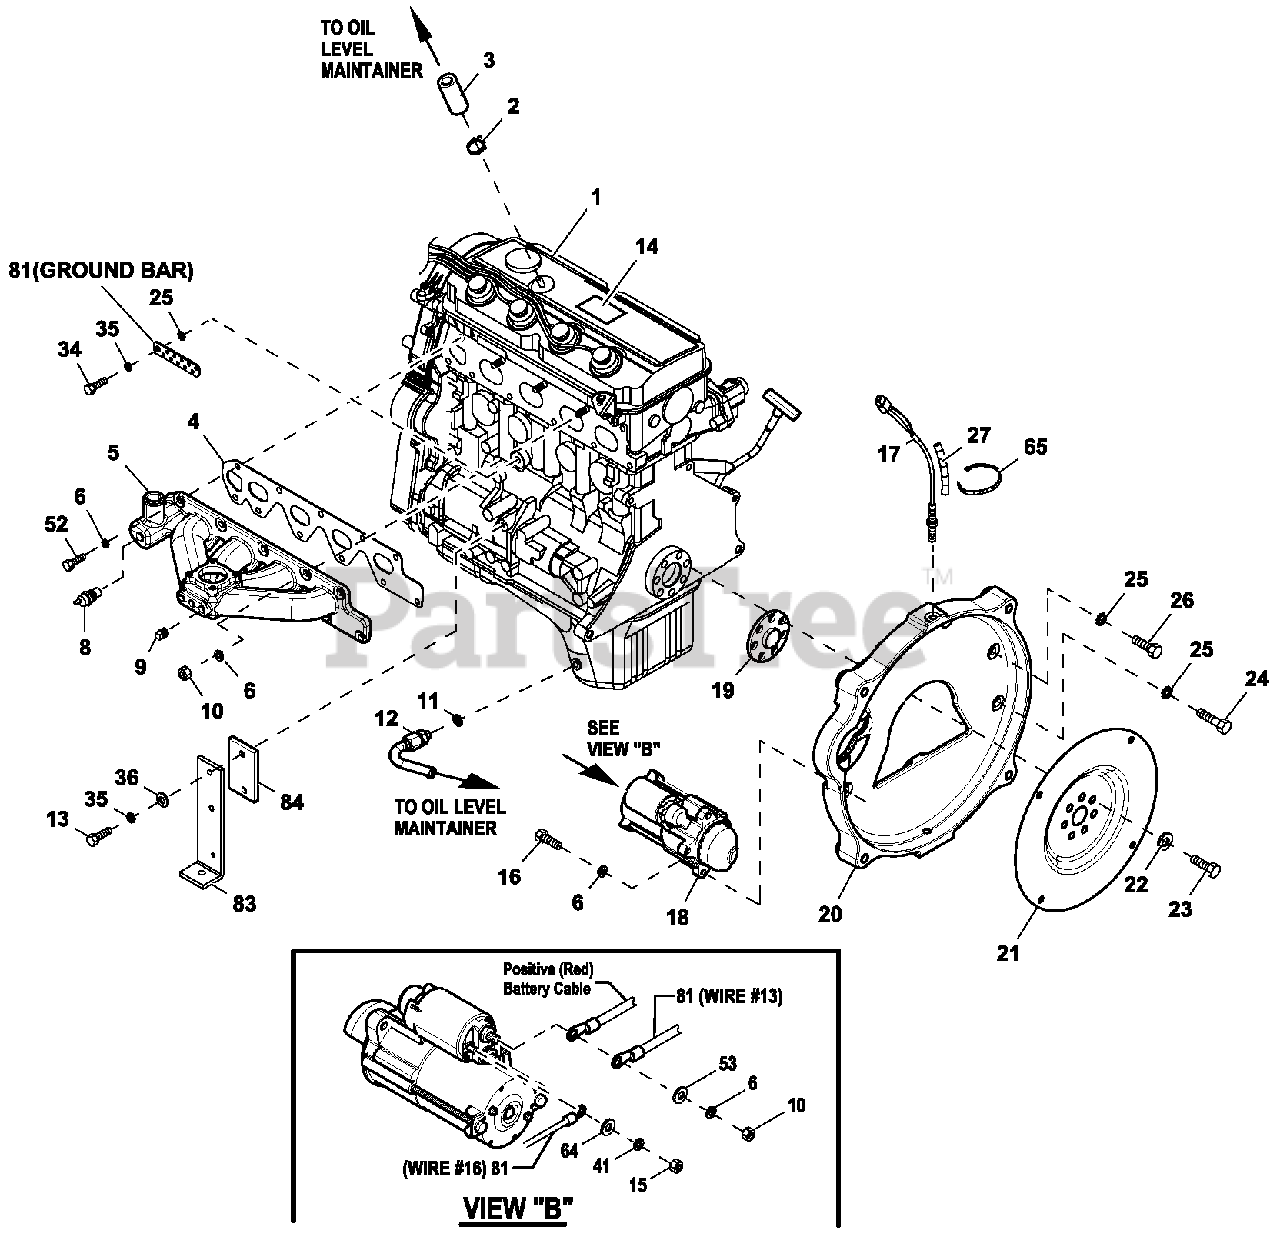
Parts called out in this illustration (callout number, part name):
1	ENGINE 2.4LG2 CERTIFIED
2	CLAMP HOSE #6 .43-.78
3	HOSE 5/16 ID TYP1SNGL HTR
4	GASKET INTAKE MANIFOLD G2
5	MANIFOLD INTAKE (MACHINED)
6	WASHER LOCK M8-5/16
7	SCREW SHC M8 -1.25 X 25
8	TEMPERATURE SENDER, DELPHI
9	PLUG STD PIPE 1/4 STEEL SQ HD
10	NUT HEX M8-1.25 G8 CLEAR ZINC
11	WASHER NYLON .565
12	TUBE OIL FITTING ASSEMBLY
13	SCREW HHCM10-1.25X40 C8.8
14	DECAL G2 IMPORT
15	NUT HEX M6-1.0 G8 CLEAR ZINC
16	SCREW SHC M8-1.25 X 30 C12.9
17	MAGNETIC PICKUP
18	MOTOR STARTER
19	SPACER 2.4L G2 FLEX PLATE
20	ADAPTER ENGINE
21	FLEX PLATE 2 POLE 2.4L G2
22	WASHER FLAT .531 ID X 1.062 OD
23	SCREW HHCM12-1.25X 20 C10.9
24	SCREW HHCM10-1.25X45 G8.8
25	WASHER SHAKEPROOF EXT 7/16 STL
26	SCREW HHCM10-1.25X30 G8.8
27	CONDUIT FLEX.25"ID(7.5"LG)
28	SHIELD INNER HEAT 2.4L TURBO
29	SCREW HHTT M6-1.0 X 12 ZINC
30	PLATE "HOT"
31	RIVET POP .125X0.337 STEEL
32	ASSEMBLY DIPSTICK G2.4L
33	ASSY DIPSTICK TUBE 2.4 G2
34	SCREW HHCM10-1.25X 20 C8.8
35	WASHER LOCK M10
36	WASHER FLAT 3/8-M10 ZINC
37	O-RING SIZE 9.0MM X 2.0MM NITR
38	TUBE TURBO OIL RETURN G2 2.4L
39	CONDUIT THERMAL FLEX 13MM ID
40	SCREW HHC M6-1.0 X 16 C8.8
41	WASHER LOCK M6-1/4
42	WASHER FLAT 1/4-M6 ZINC
43	BRACKET EXH MANIFOLD 2.4 TURBO
44	HEAT SHIELD TURBO 2.4L
45	BRACKET HEAT SHIELD 2.4L
46	SCREW HHC M8-1.25X 16 C8.8
47	GASKET EXHAUST MANIFOLD
48	SCREW HHC M10-1.5X 120 C8.8
49	ALTERNATOR DC W/OUT PULLEY
50	PULLEY DC ALTERNATOR
51	SPACER DC ALTERNATOR PULLEY
52	SCREW HHC M8-1.25X 25 G10.9
53	WASHER FLAT 5/16-M8 ZINC
54	SCREW HHC M8-1.25X35 G8.8
55	SCREW SHC M14-1.5X 35 G10.9
56	ADAPTER 2.4L CRANKSHAFT MACH
57	POLY V-BELT G2
58	CAM SENSOR PIN ASSY
59	COVER CAM GEARG2RK
60	BRACKET ASM-2.4L COIL G2
61	SCREW HHC M8-1.25X65 C8.8
62	SCREW HHC M8-1.25X70 G8.8
63	NUT HEX M10-1.25 G 8YELCHR
64	WASHER FLAT M6
65	TIE WRAP UL 7.4"X .19" BLK
66	COIL-2.4LG2 IGNITION
67	WASHER FLAT #10 ZINC
68	WASHER LOCK #10
69	SCREW HHM #10-32X1-1/4
70	O-RING 2.5"X 2.75"X 1/8" VITON
71	ADAPTOR OIL FILTER 2.4L G2
72	HARN LOW OIL PRESS SWITCH A SSY
73	ADAPTOR 45D JIC37 1/2NPT X 3/4
74	O-RING 1 "X 1.25" X 1/8" VITON
75	NUT OIL FILTER ADAPTOR 2.4L G2
76	PLUG SPARK
77	SHIELD HEAT IGNITION COIL 2.4L
78	SPARK PLUG WIRE SET 2.4L G2 IG
79	MANIFOLD EXH 60K G2 TURBO (MA)
81	HARN ENG G2.4L G2 PROTECTOR
82	NUT HEX M10-1.5 G8YEL CHR
83	SUPPORT LH ENGINE 2.4L
84	SPACER LH ENGINE MOUNT
85	SUPPORT RH ENGINE 2.4L
